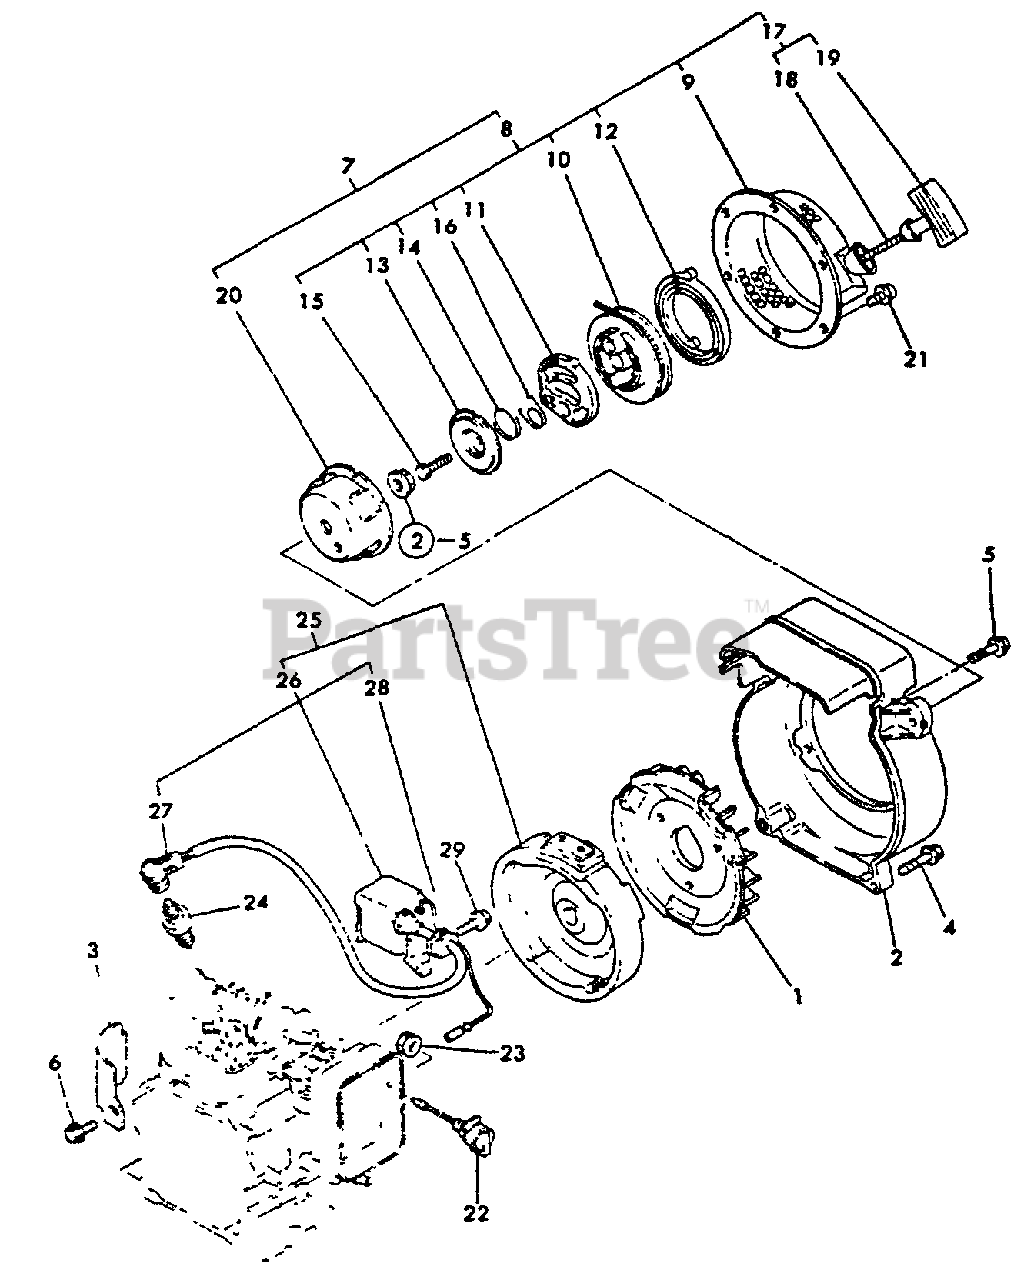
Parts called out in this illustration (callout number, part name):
1	FAN
2	COVER, FAN
3	SHIELD, CYLINDER
4	BOLT - 6X25
5	BOLT - 6X30
6	BOLT - 6X8 -- PLATED
7	STARTER ASSY
8	STARTER ASSY
9	STARTER CASE ASSY
10	REEL, ROPE
11	RATCHET
12	SPRING
13	PLATE, FRICTION
14	SPRING, FRICTION
15	BOLT
16	SPRING, RETURN
17	ROPE ASSY
18	ROPE
19	GRIP, STARTER
20	PULLEY, STARTER
21	BOLT - 6X8 -- PLATED
22	IGNITION SWITCH ASSY
23	NUT - 8
24	SPARK PLUG -- BPM-8Y
25	FLYWHEEL MAGNETO ASSY
26	COIL, IGNITION
27	CAP, SPARK PLUG
28	GROMMET
29	BOLT - 6X25
